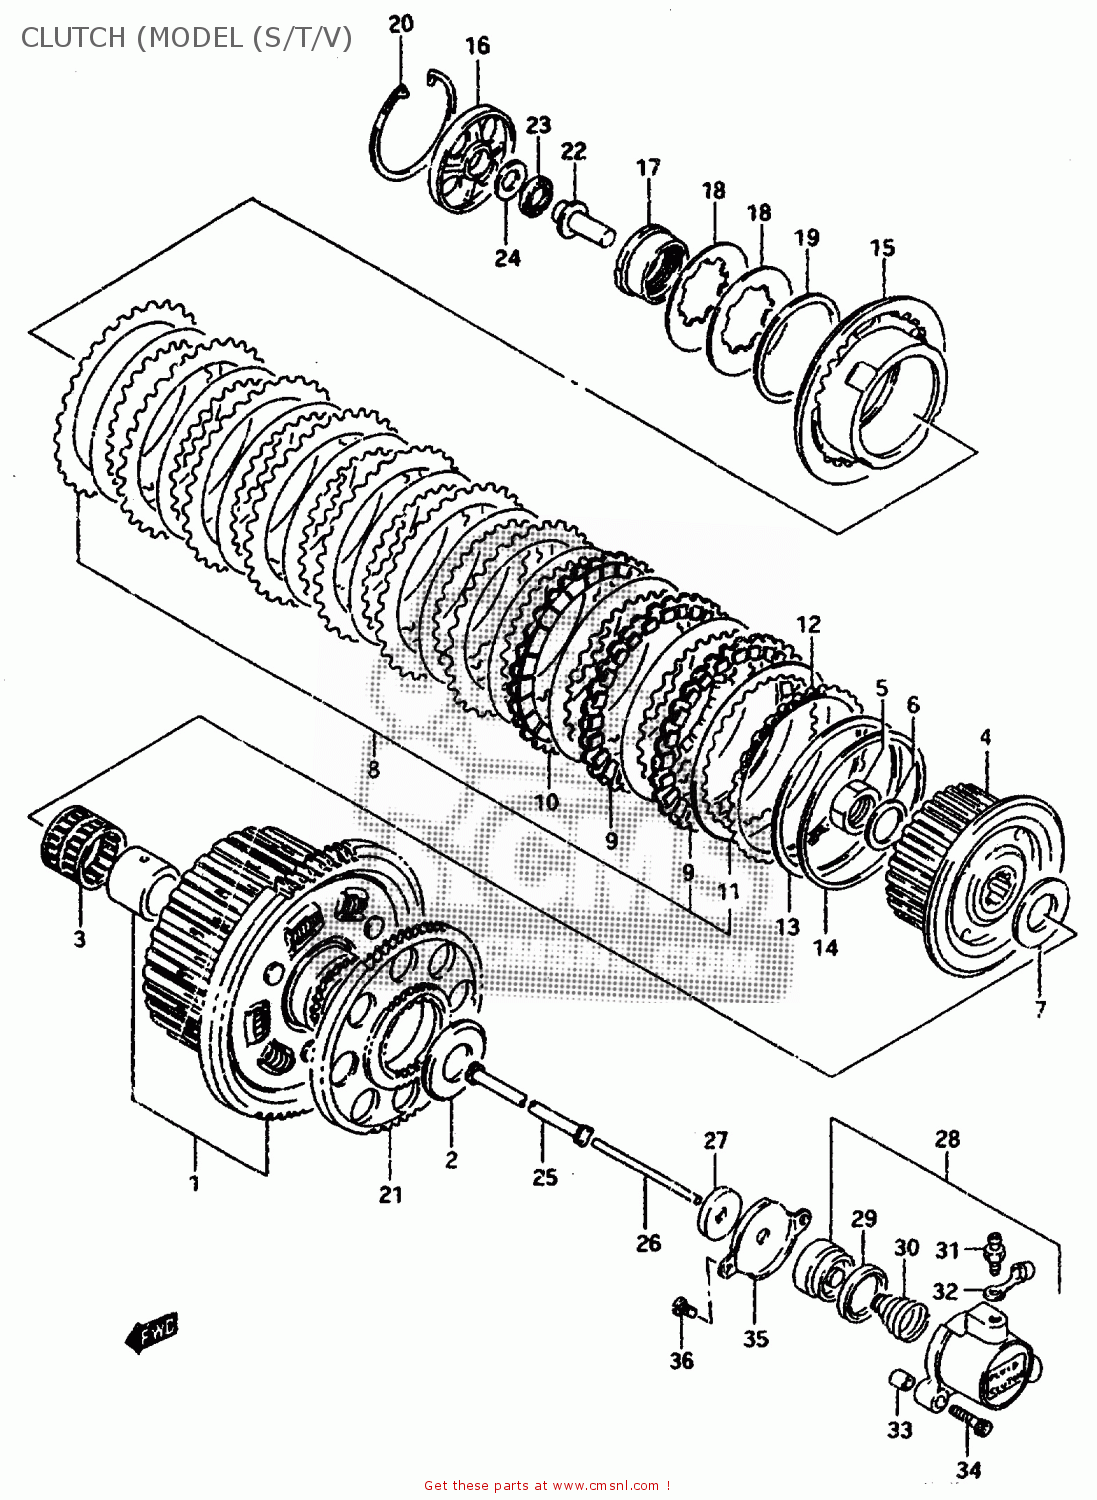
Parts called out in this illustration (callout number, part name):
1	GEAR SET,PRIMARY DRIVE
2	WASHER(25X54X2.5)
3	BEARING(35X40X35.8)
4	HUB,CLUTCH SLEEVE
5	NUT
6	WASHER
7	WASHER(25X50X2.5)
8	PLATE ASSY,CLUTCH
9	PLATE,CLUTCH DRIVE NO.2 (NAS)
10	PLATE,CLUTCH DRIVE NO.1 (NAS)
11	PLATE,CLUTCH DRIVEN (NAS)
12	PLATE,CLUTCH DRIVE NO.2
13	WASHER
14	SEAT,CL SLEEVE HUB WAVE WASHER
15	DISC,CLUTCH PRESSURE
16	LIFTER,CLUTCH PRESSURE DISC
17	HOLDER,CLUTCH SPRING
18	WASHER
19	SEAT,CLUTCH SPRING
20	CIRCLIP
21	GEAR,GENERATOR DRIVE
22	PIECE,CLUTCH PUSH
23	BEARING(15X28X2)
24	WASHER(15.5X28X1)
25	ROD,CLUTCH
26	ROD,CLUTCH PUSH,L
27	SEAL,OIL(6X34X5.5)
28	CYLINDER,CLUTCH RELEASE
29	CUP
30	SPRING,CLUTCH CYLINDER
31	BLEEDER
32	CAP,BLEEDER
33	PIN
34	BOLT,CL.COVER
35	SCREW
36	SCREW
